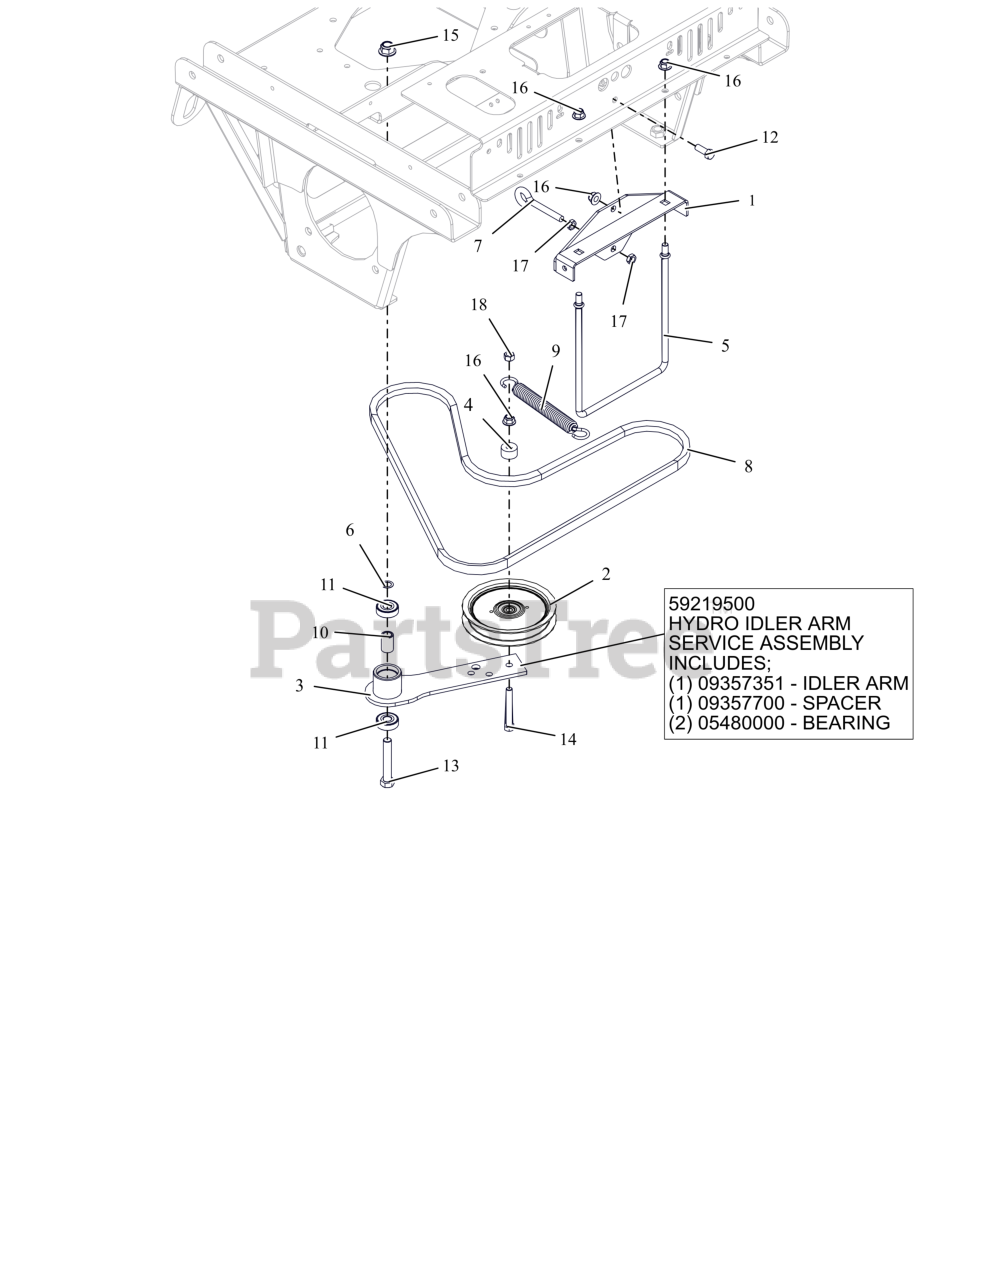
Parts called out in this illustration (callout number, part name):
1	SPRING ANCHOR BRKT WMT - BLACK
2	IDLER, FLAT-5.00X.75
3	HYDRO DRIVE IDLER ARM WMT- BLK
3	KIT, HYDRO IDLER ARM PT200/400
4	SPACER .390X1.000X.562
5	ROD, BRAKE MTG
6	WASHER, .500X.750X.020 THRUST
7	BLT-EYE .375-16X2.50 YWZC
8	V-BELT, COGGED B-RAW EDGE
9	SPRING, EXTENSION
10	SPACER .510 X .75 X 1.1485
11	BRG-BALL .500X1.38X.437
12	BLT,HEX .38-16X1.00 G5 ZCC
13	BLT, HEX .50-13X3.00 G5 ZCC
14	BLT, HEX .38-16X2.75 G5 ZCC
15	NUT,NYL-FLG .50-13 GF ZCC
16	NUT,NYL-FLG .38-16 GF ZCC
17	NUT-JAM .375-16 G2 ZCC
18	NUT-LK-CTR .38-16 ZC120
